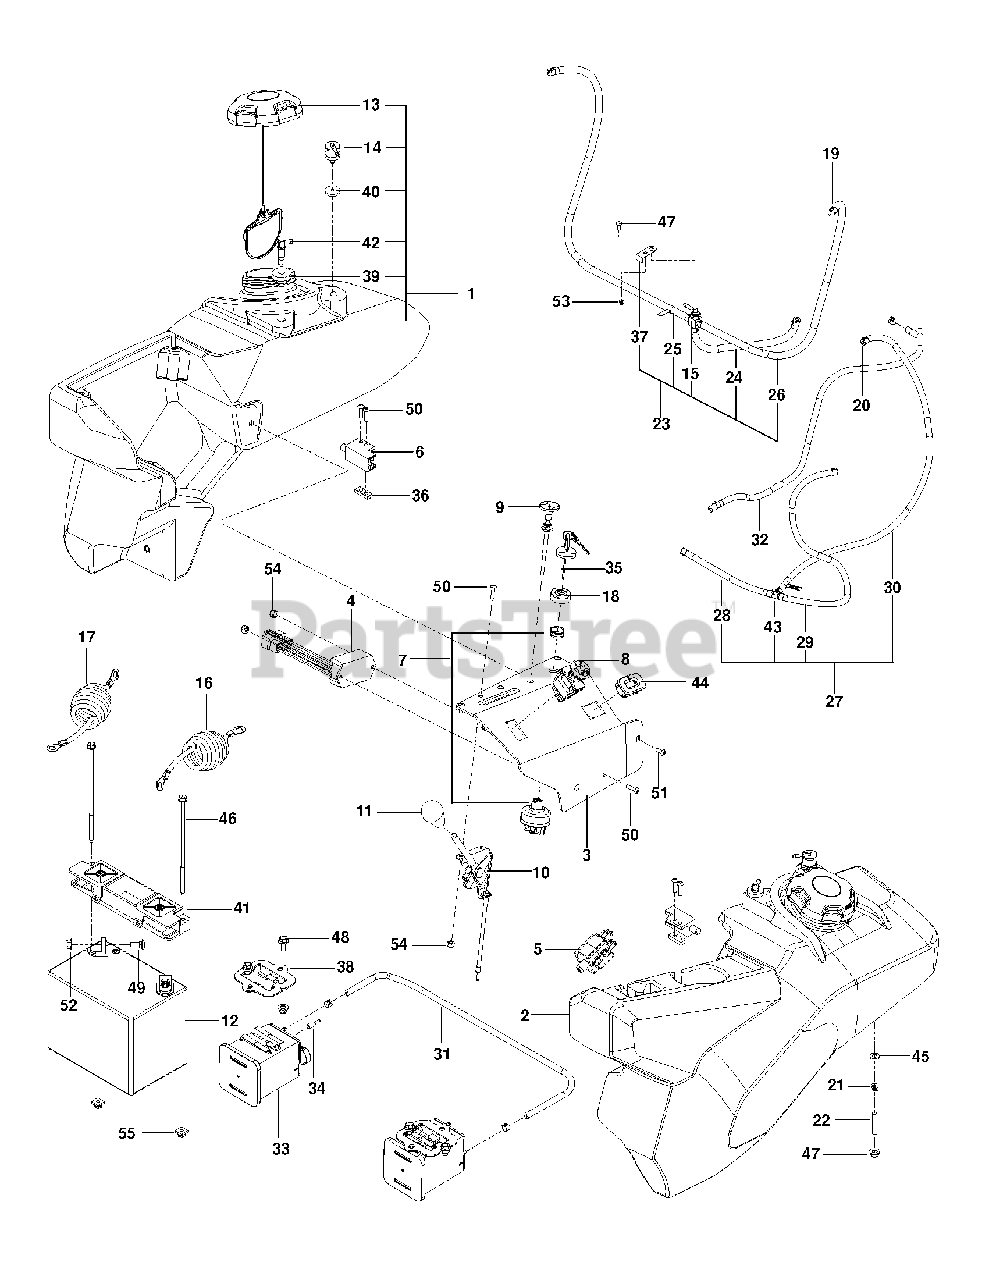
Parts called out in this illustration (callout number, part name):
3	PANEL, CONTROL GAS BLACK
4	TIMER, SEAT
5	SWITCH, BRAKE 3P
7	SWITCH, IGNITION, INDAK
8	SWITCH, PTO 10 AMP
9	CABLE, CHOKE, 38
10	CABLE, THROTTLE, 38
11	KNOB - SHIFT
13	CAP, FUEL
14	VALVE.FUEL.CHECK
15	FUEL VALVE
16	POST.CABLE LONG
17	NEG. CABLE, 28"
19	HOSE CLAMP
20	CLAMP, HOSE
22	STUD, 5/16C
24	FUEL LINE 5"
26	FUEL LINE 24"
28	HOSE, 3/16" VAPOR, 7-1/2"
29	HOSE, FUEL, 3/16" X 20"
30	HOSE, VAPOR 3/16 X 39"
31	HOSE, VAPOR 3/16 X 30"
33	CANNISTER, CARBON
34	CAP, VINYL
35	KEY, IGNITION
36	TAPPED PLATE
37	BRACKET FUEL VALVE
38	BRACKET, CANISTER
39	RUBBER GROMMET
40	GROMMET, CHECK VALVE
41	BATTERY HOLD DOWN
45	FLAT WASHER 5/16 SAE
46	BOLT - 1/4-20 X 7.5
47	HCS 1/4C X 3/4 HCS
48	HHFS 5/16-18 X 3/4
49	BOLT 5/16C X 3/4" CARRIAGE
50	SCR #10-24 X .75 SKT HD BLK
51	SCR #10-24 X 3/8 SKT HD BLK OX
52	5/16-18 NYLOC FLANGE NUT
53	JAM NUT 1/4C
54	NUT 10-24 NYLOC
55	PUSH NUT-NYLON
